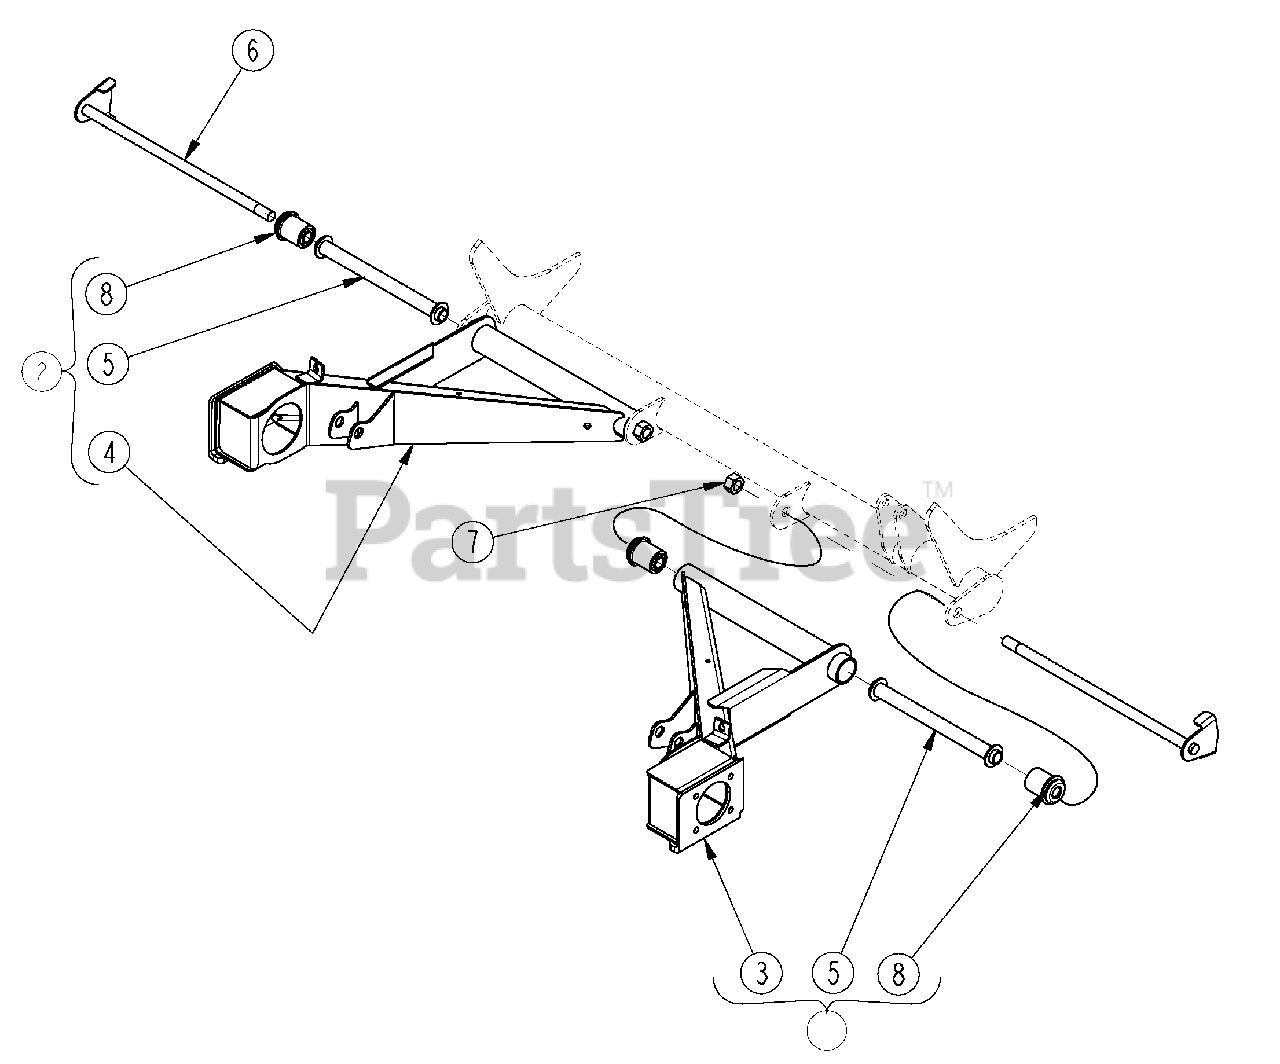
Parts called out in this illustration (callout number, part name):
1	TRAILING ARM RH ASSY
2	TRAILING ARM LH ASSY
3	TRAILING ARM RH WELDMENT
4	TRAILING ARM LH WELDMENT
5	CENTER PIVOT TUBE WELDMENT
6	TRAILING ARM PIVOT BOLT WLDMNT
7	NUT HEX TOP LOCK 9/16-12 YLW
8	BUSHING IDLER ARM RUBBER
